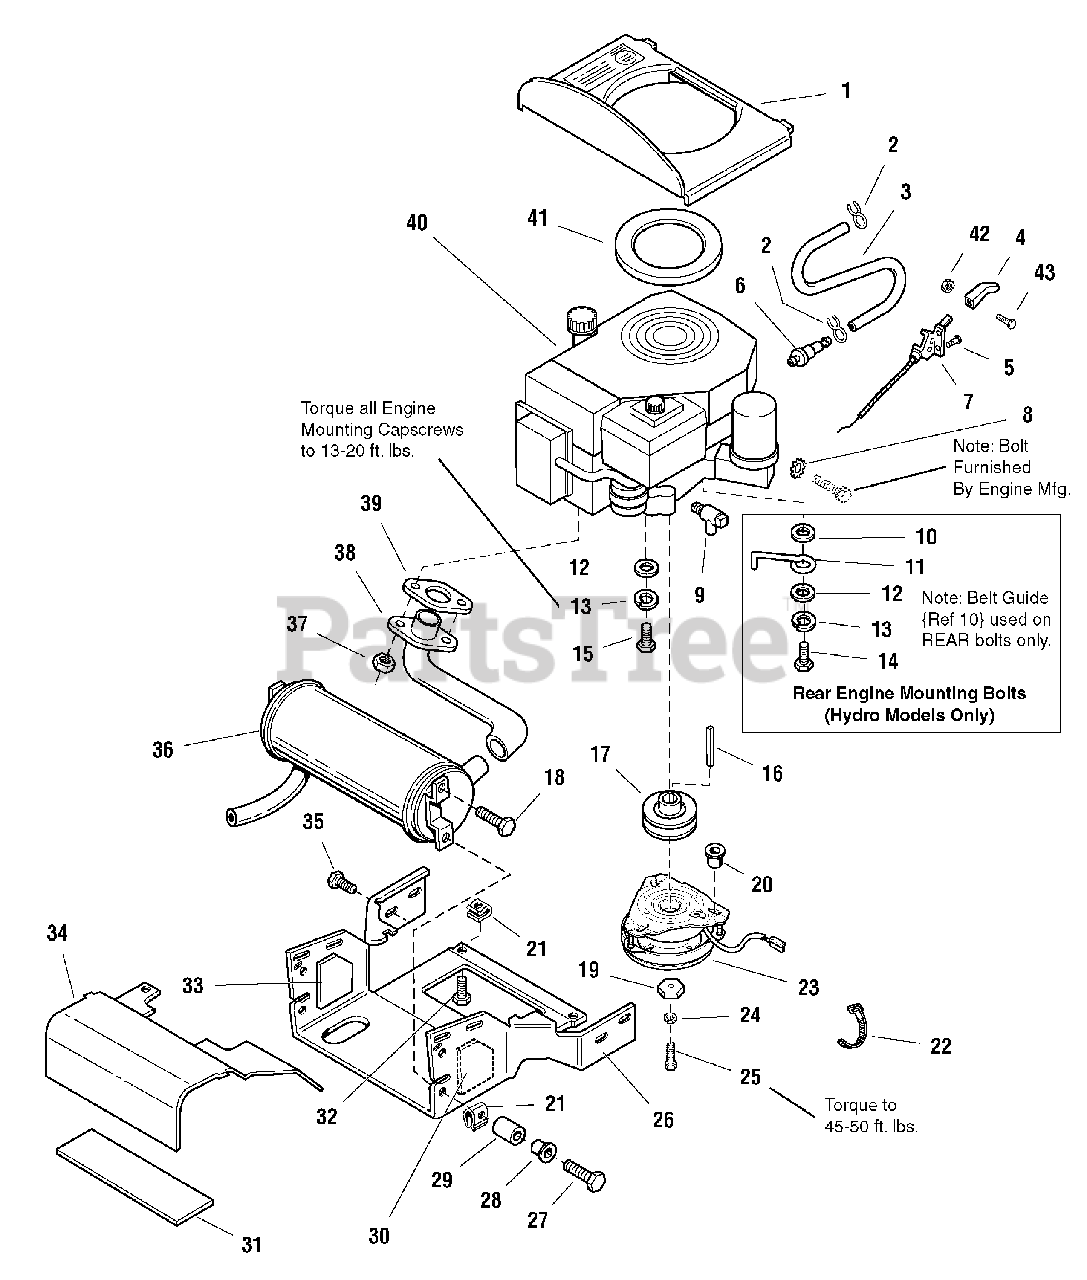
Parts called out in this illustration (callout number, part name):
2	CLAMP, Hose Type E
5	CAPSCREW, Hex Washer Head, 1/4-14 x 5/8
6	FUEL FILTER
7	CABLE, Control Throttle, 14"
8	LOCKWASHER, External Tooth, 3/8
9	VALVE, Shut Of
10	WASHER, 7/16
12	WASHER, 5/16
13	LOCKWASHER, 5/16
14	CAPSCREW, M08-1.25 x 40MM
15	CAPSCREW, M08-1.25 x 30MM
18	CAPSCREW, Hex Washer Head Taptite, 1/4-20 x 3/8
19	WASHER, Hex, 7/16
20	SLEEVE, Clutch Anchor
21	NUT, Speed, 5/16-18
23	CLUTCH, Electric
24	LOCKWASHER, 7/16
25	CAPSCREW, 7/16-20 x 3
26	DUCT, Muffler Lower
27	CAPSCREW, Hex Head Flange Lock, 5/16-18 x 1-1/4
30	INSULATION, LH
31	INSULATION, Foam, 6 x 11-3/8
32	CAPSCREW, Hex Head Flange Lock, 5/16-18 x 3/4
33	INSULATION, RH
34	DUCT, Muffler Upper
34	DUCT, Muffler Upper, (Export)
35	CAPSCREW, Hex Washer Head Taptite, 5/16-18 x 1/2
36	MUFFLER (Domestic)
36	MUFFLER (Export)
37	NUT
38	PIPE, Manifold
39	GASKET
42	NUT, #10-24 Nylon
43	SCREW, #10-24
